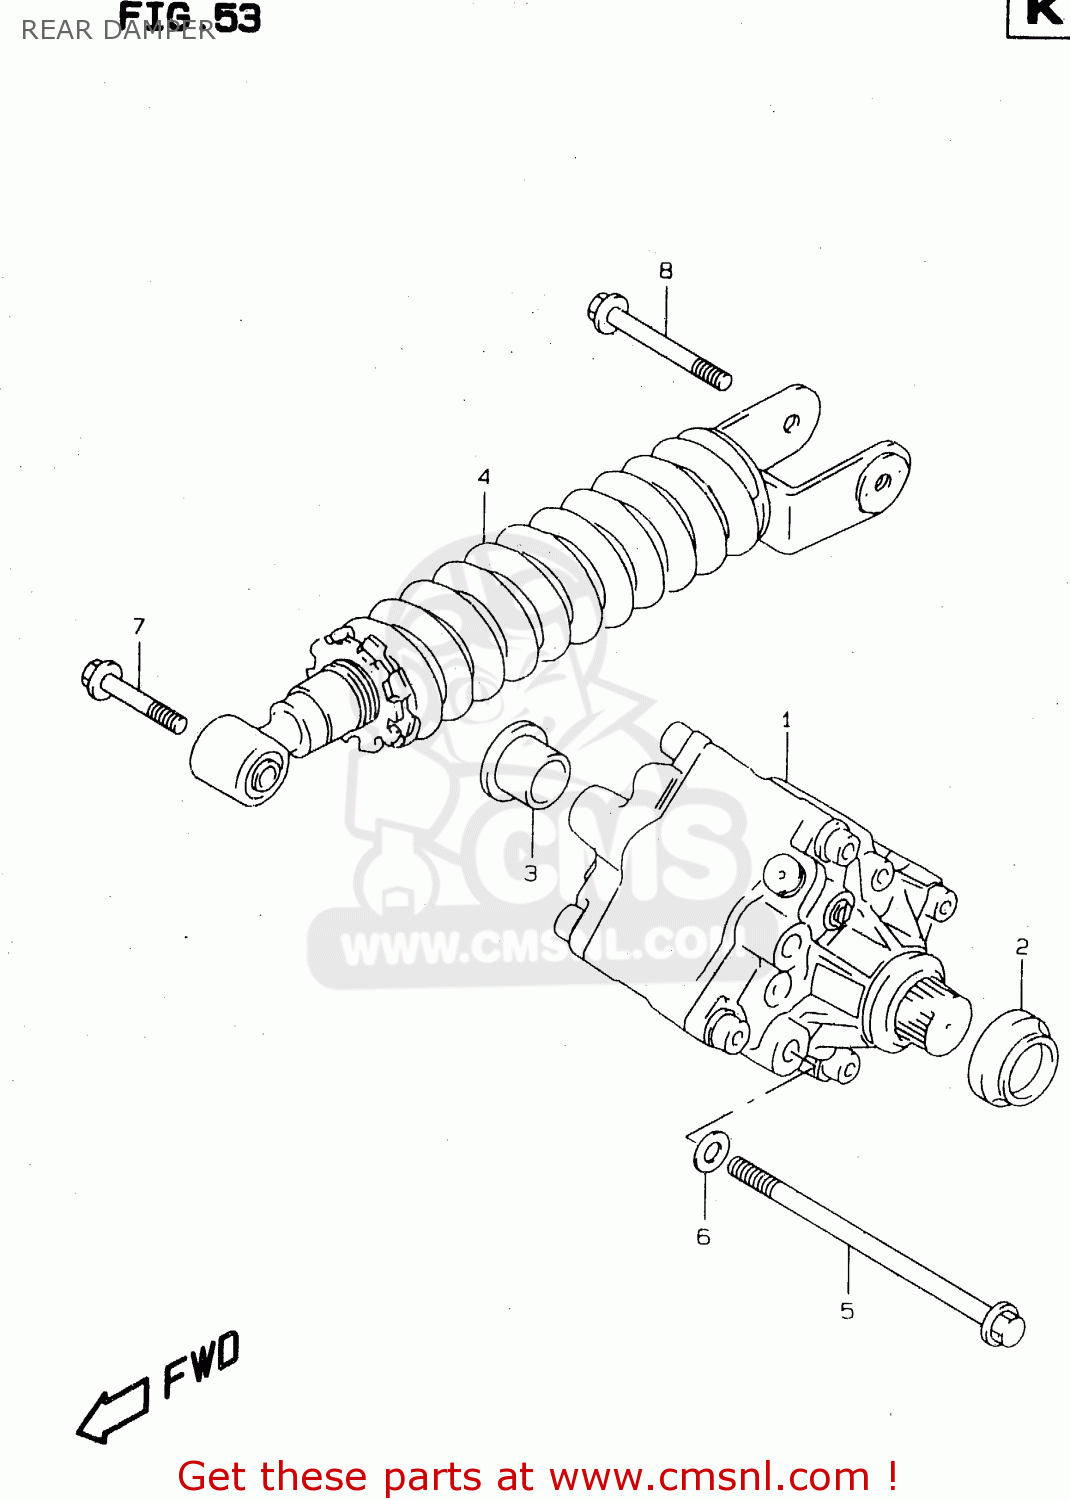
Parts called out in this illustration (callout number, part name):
1	DAMPER ASSY,RR
2	CAP
3	CAP
4	UNIT ASSY,RR SPRING
5	BOLT(10X130)
6	WASHER
7	BOLT(10X54)
8	BOLT(10X60)
